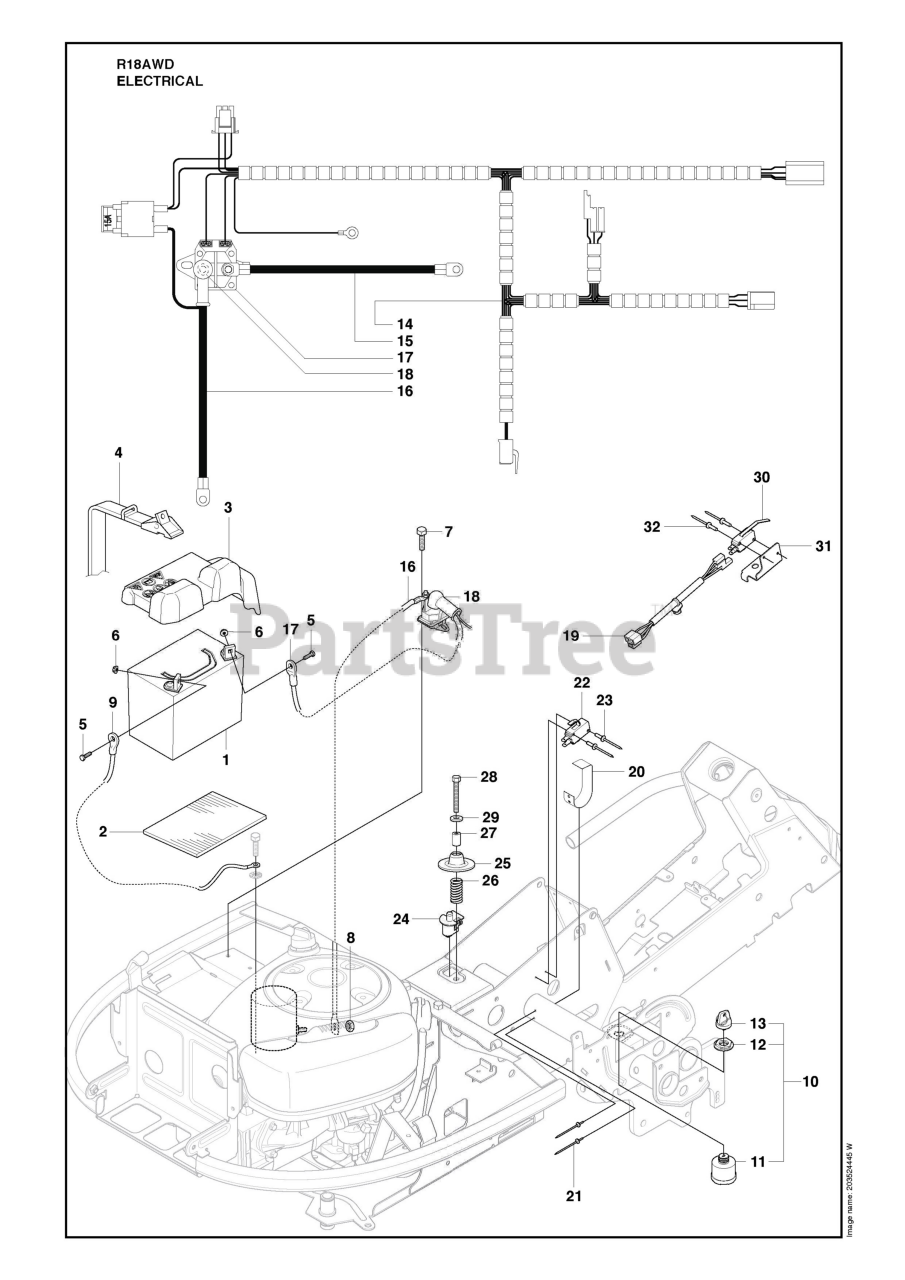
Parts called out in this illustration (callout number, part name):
5	SCREW EHHM
10	IGNITION SWITCH
11	IGNITION SWITCH
13	IGNITION KEY
18	NUT
19	WIRING
22	%BRAKER
27	SPACER TUBE
28	SCREW
29	WASHER BRB 8.4X17
30	RP MICRO SWITCH
